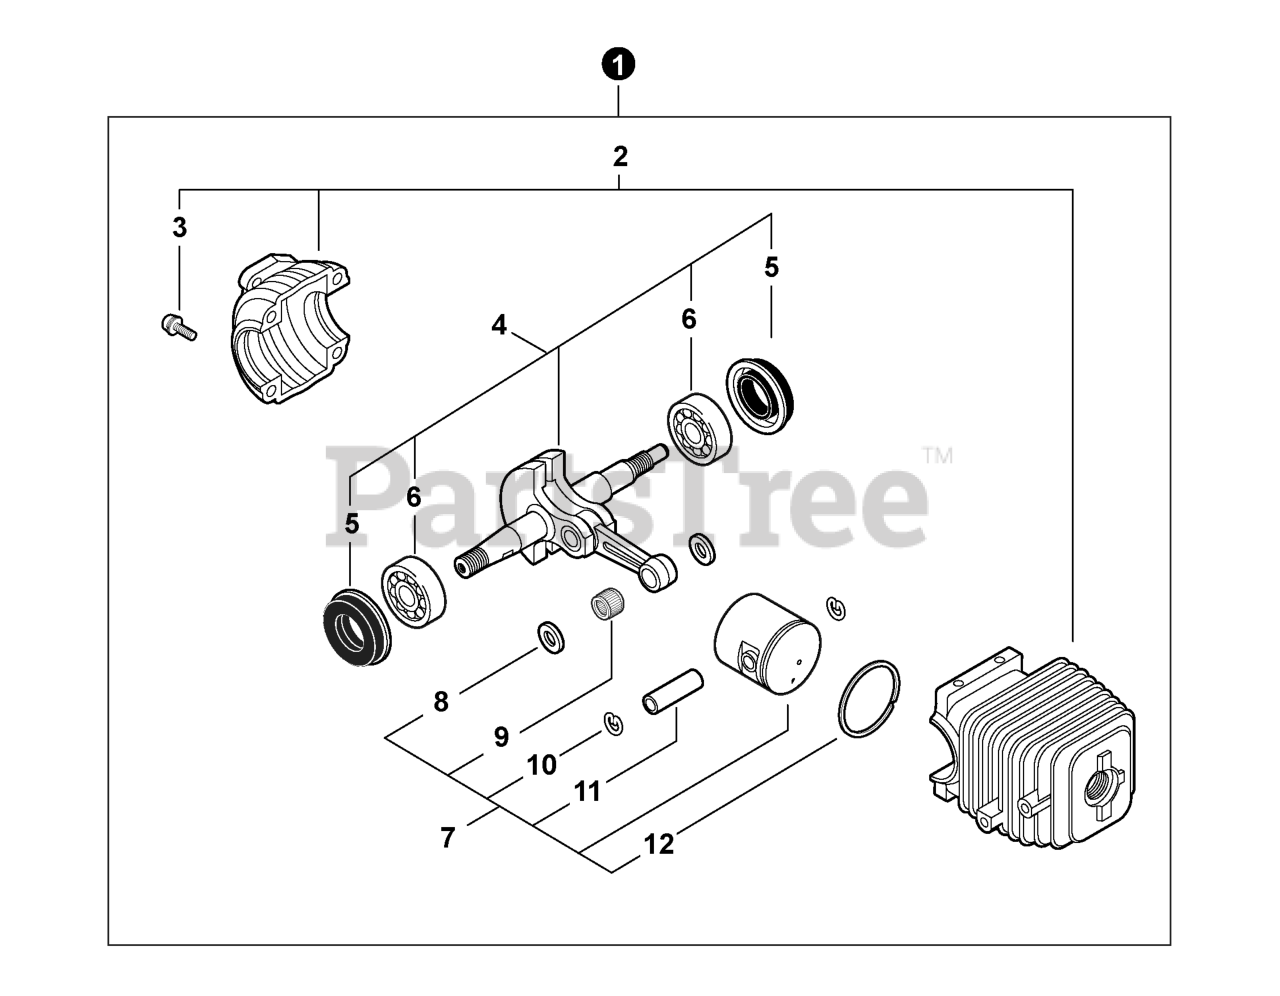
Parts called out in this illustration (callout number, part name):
1	SHORT BLOCK
2	CRANKCASE KIT
3	SCREW 5x25
4	CRANKSHAFT ASSY
5	SEAL, OIL 12
6	BEARING, BALL 6201
7	PISTON KIT
8	WASHER, THRUST
9	BEARING, NEEDLE 8
10	RING, SNAP
11	PIN, PISTON
12	RING, PISTON
